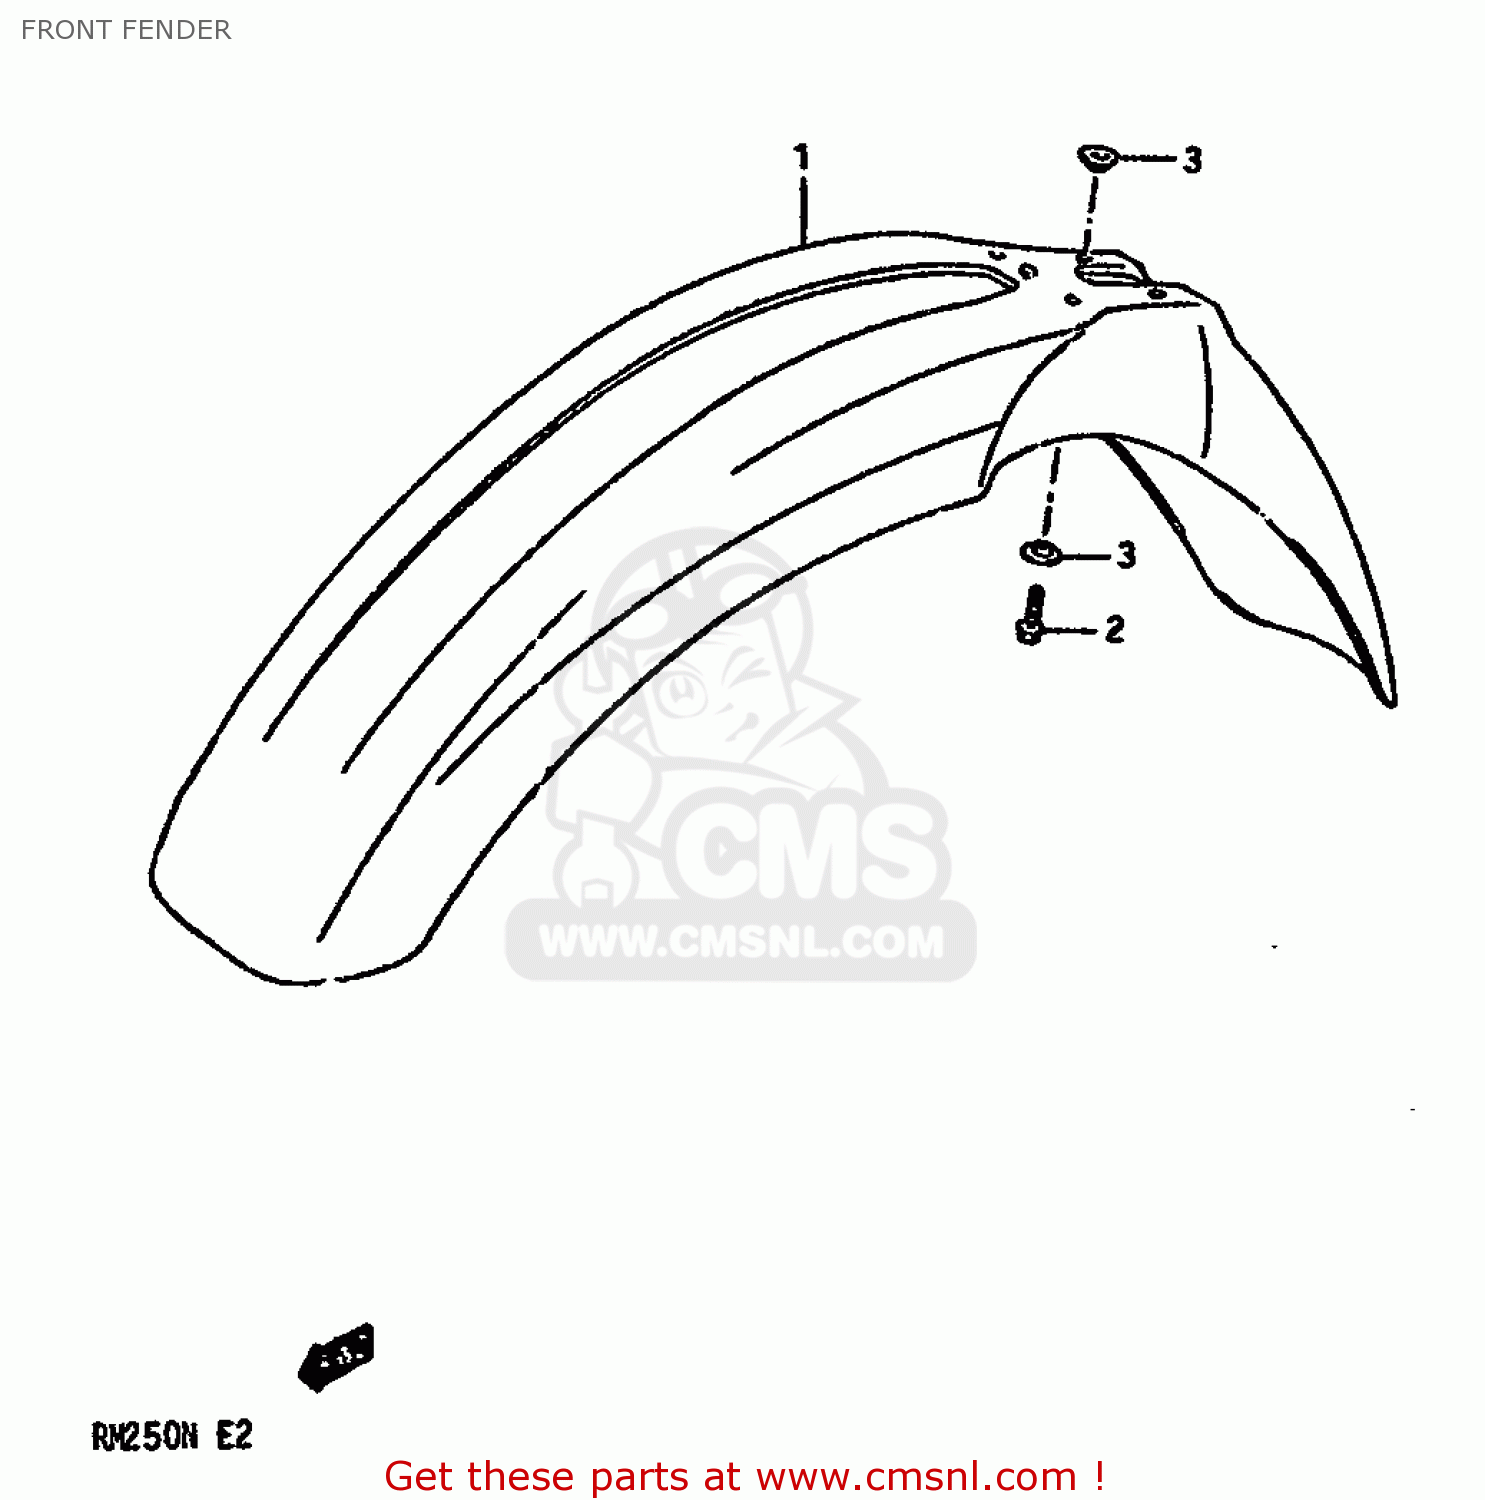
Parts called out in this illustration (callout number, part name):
1	FENDER,FRONT
2	BOLT
3	WASHER
